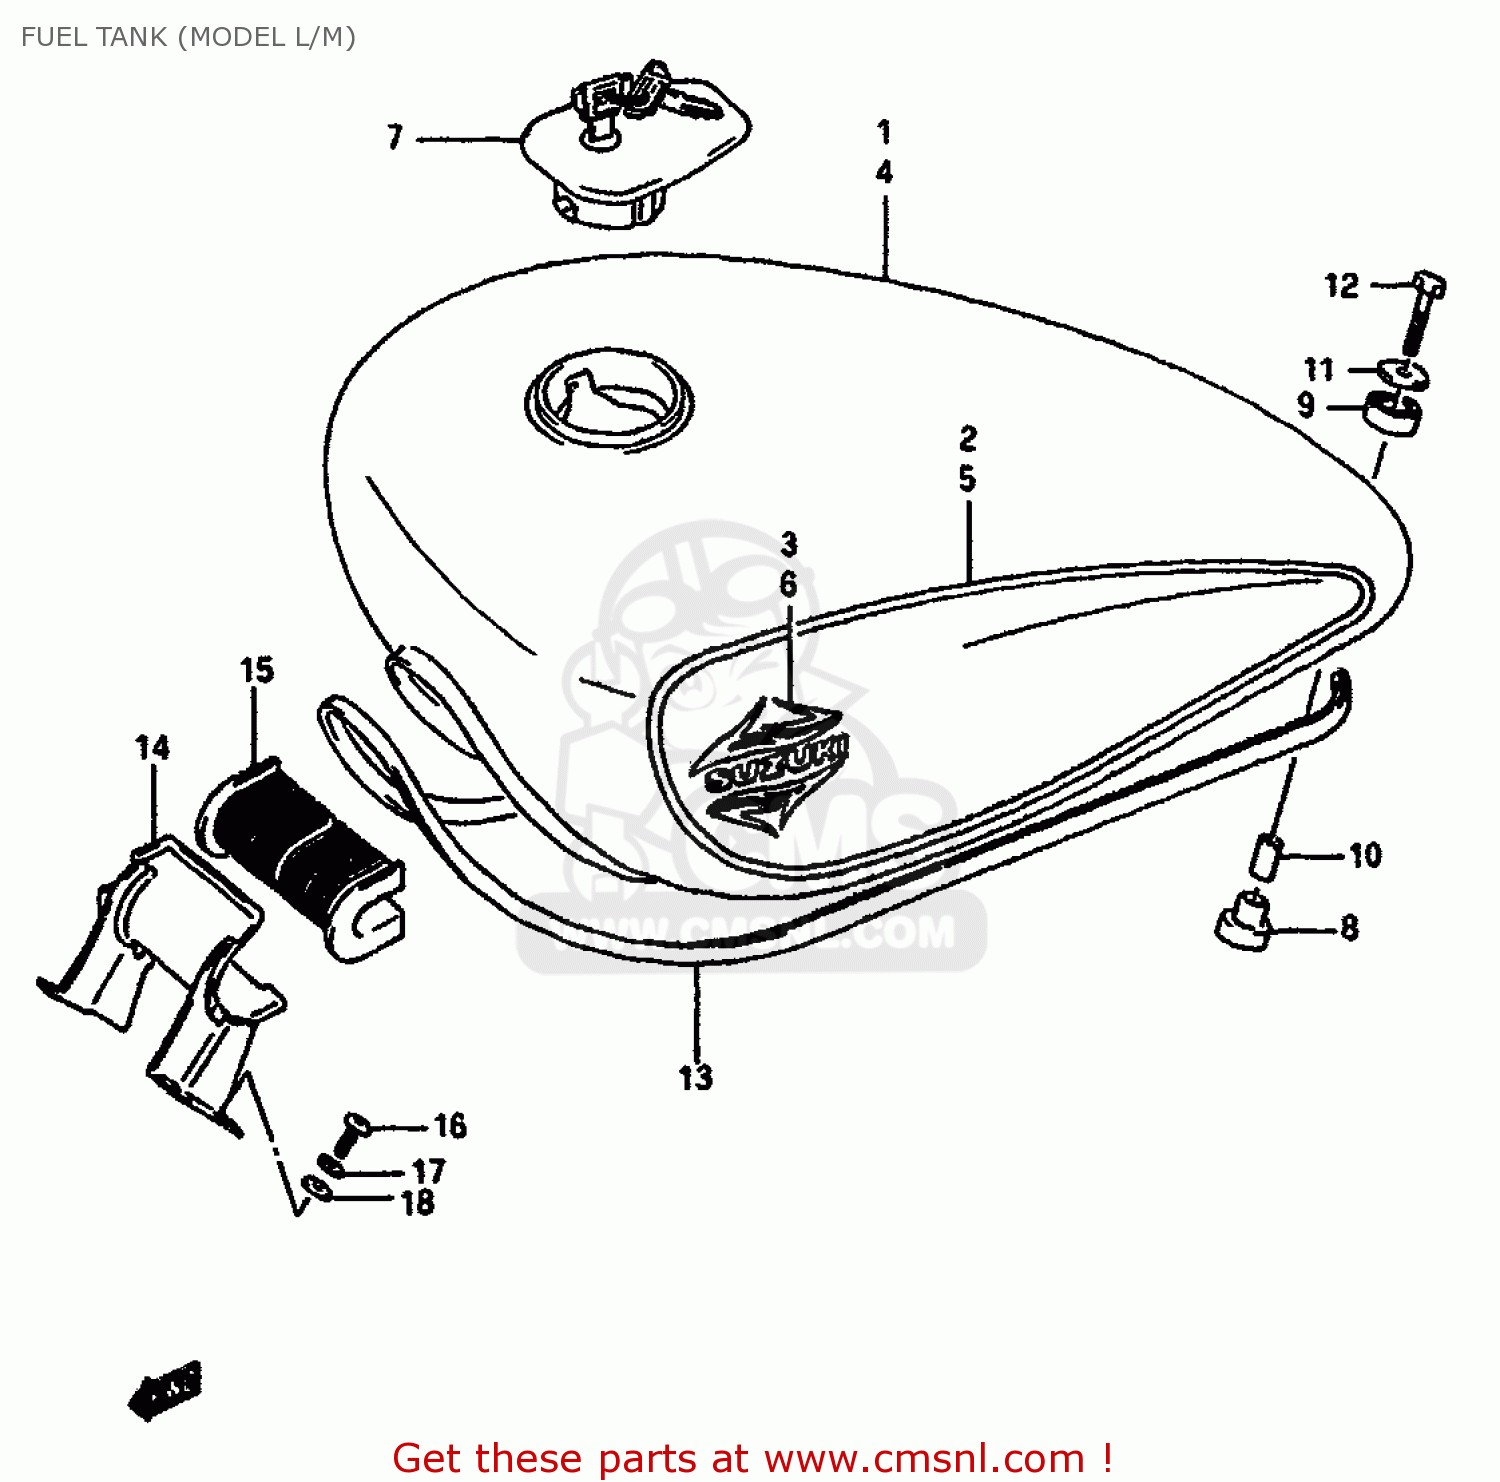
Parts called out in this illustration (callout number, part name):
1	TANK ASSEMBLY,FUEL
2	TAPE SET,FUEL TANK
3	EMBLEM
4	TANK ASSEMBLY,FUEL
5	TAPE SET,FUEL TANK
6	EMBLEM,FUEL TANK
7	CAP SET,FUEL TANK
8	CUSHION
9	CUSHION
10	SPACER (6.4X9X21.5)
11	WASHER (6.5X24X1.6)
12	SCREW
13	MOLDING,FUEL TANK
14	BRACKET COMP,FUEL TANK
15	WASHER,LOCK
16	SCREW
17	WASHER,LOCK
18	WASHER
